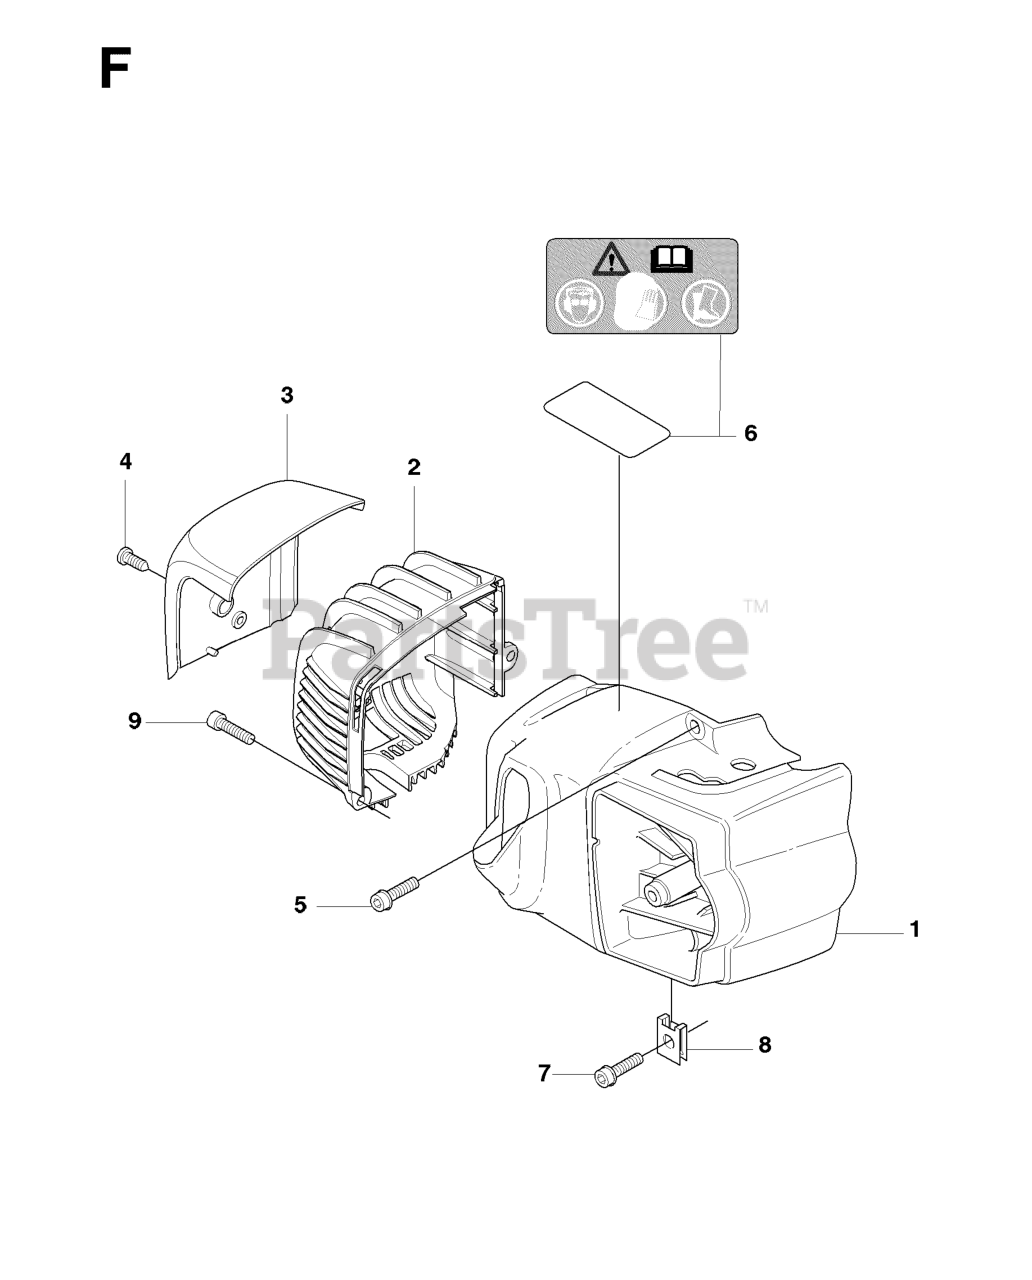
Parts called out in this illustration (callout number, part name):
2	RP MUFFLER COVER
3	MUFFLER SHIELD
9	SCREW W/ LOCKING FLUID
